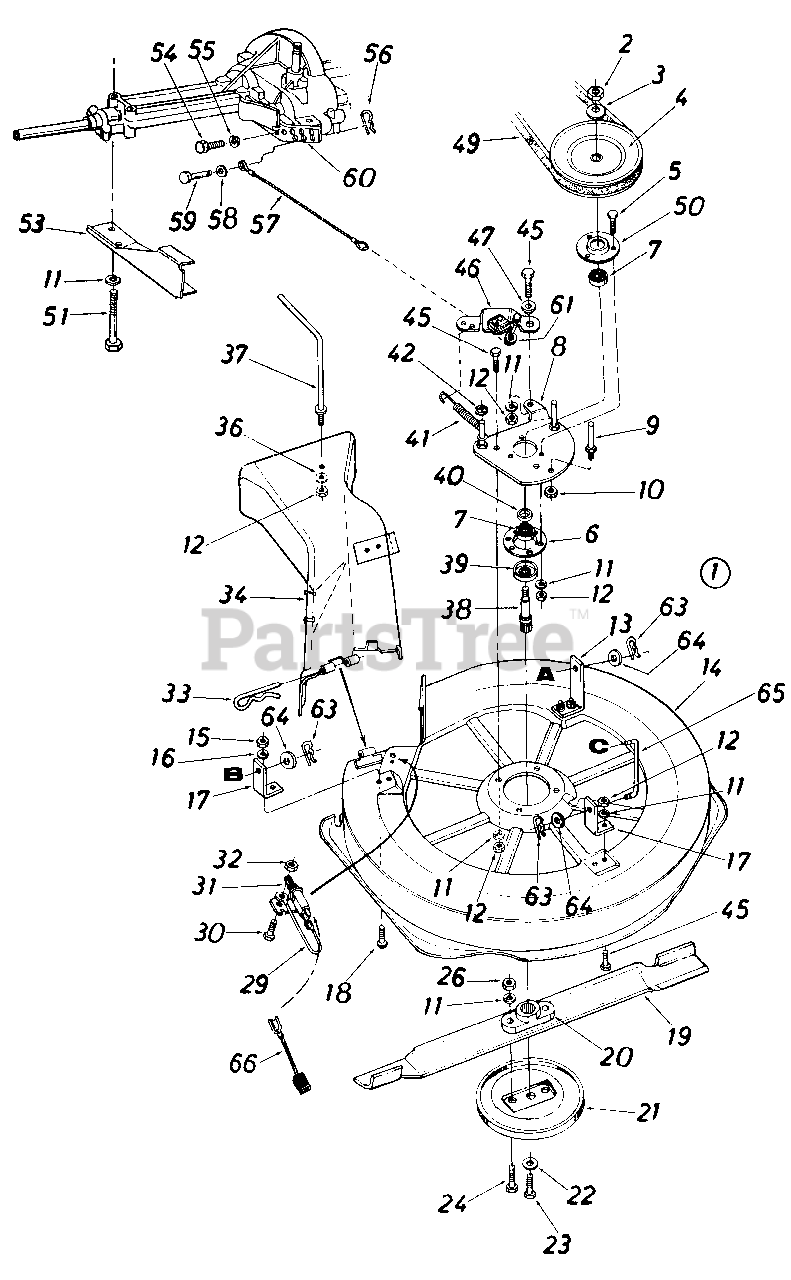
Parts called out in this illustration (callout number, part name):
1	30" R.D. Deck Ass'y. Comp.
2	Hex Jam Nut 5/8-18 Thd.
3	Bell-Wash. .630" I.D. x 1.25"
4	5/8 V-Pulley .75" I.D. x .7"
5	Hex Sems 5/16-18 x .62" Lg.
6	Brg. Housing 1.85" I.D.
7	Ball Brg. .787" I.D.
8	Spindle Mtg. Plate
9	Stud 3/8-16 x 2.75" Lg.
10	Hex Jam Nut 3/8-16 Thd.
11	L-Wash. 5/16" I.D.
12	Hex L-Nut 5/16-18 Thd.
13	Hanger Brkt. 2.92"
17	Hanger Brkt. 1.92"
18	Truss Mach. Scr. 5/16-18 x .75" Lg.
19	30" High Lift Blade
20	Blade Adapter
21	Scalp Plate
22	L-Wash. 318" I.D.
23	Hex Bolt 3/8-24 x 1.0
24	Hex Bolt 5/16-24 x 1.0" Lg.
26	Hex Nut 5/16-24 Thd.
29	Electrical Wire
30	Hex Bolt 1/4-20 x .50" Lg.
31	Safety Switch
32	Hex Nut 1/4-20 Thd.
33	Internal Cotter Pin
34	R.D. Chute Deflector
36	L-Wash. .32" I.D. x .62" O.D.
37	90ø Rod 5/16-18 Thd.
38	Blade Spindle 5.20
39	Bearing Shield
41	Extension Spring
42	Push Speed Nut
45	Hex Bolt 5/16-18 X .75"
46	Blade Brake Brkt. Ass'y.
47	Shoulder Spacer .500' Dia.
49	' 'V' '-Belt 1/2 " x 52 Lg.
50	Open Brg. Housing
51	Hex Bolt 5/16-18 X 2.75
53	Lower Outside Belt Guard
54	Hex Bolt 1/4-20 X .62 Lg.
55	L-Wash. 1/4" l.D.
56	Int. Cot. Pin 5/16" Dia.
57	Brake Cable 11.75" Lg.
58	Fl-Wash. .281" l.D. x .50
59	Clevis Pin 1/4" Dia.
60	Lower Inside Belt Guard
61	Cap Speed Nut 1/4" Rod
63	Int. Cotter Pin 1/2 Dia.
64	Fl-Wash. .531" l.D. x ,930"
65	Deck Link 3.9" Lg.
